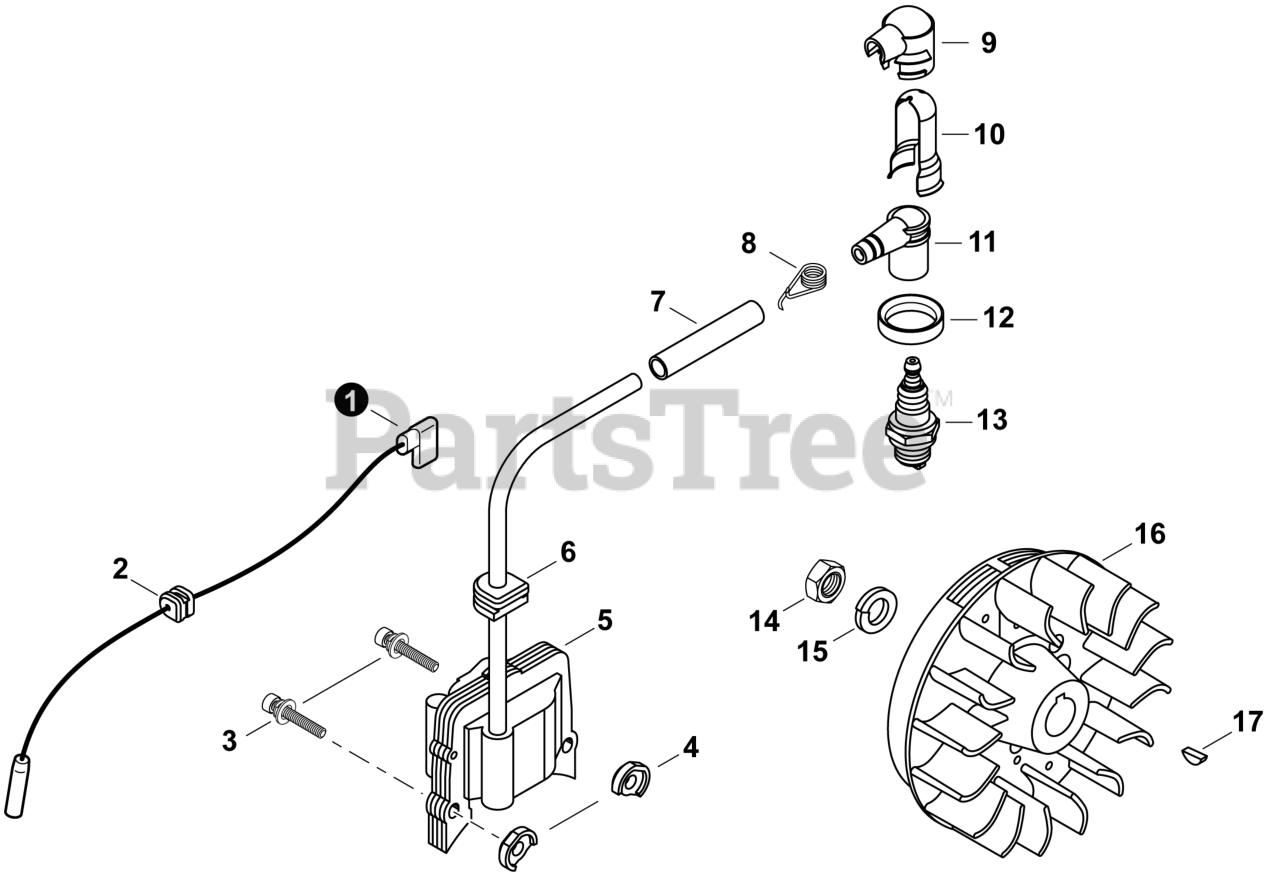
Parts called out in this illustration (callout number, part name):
1	LEAD - IGNITION
2	GROMMET, LEAD
3	SCREW 4x22
4	COLLAR 4
5	COIL, IGNITION
6	GROMMET
7	TUBE, INSULATOR
8	TERMINAL, SPARK PLUG
9	COVER, CAP
10	SHIELD, SPARK PLUG
11	CAP, SPARK PLUG
12	SEAL, SPARK PLUG
13	SPARK PLUG - BMR6A
14	NUT 10x1.25
15	WASHER, SPRING 10
16	FLYWHEEL
17	KEY, WOODRUFF 3x10
